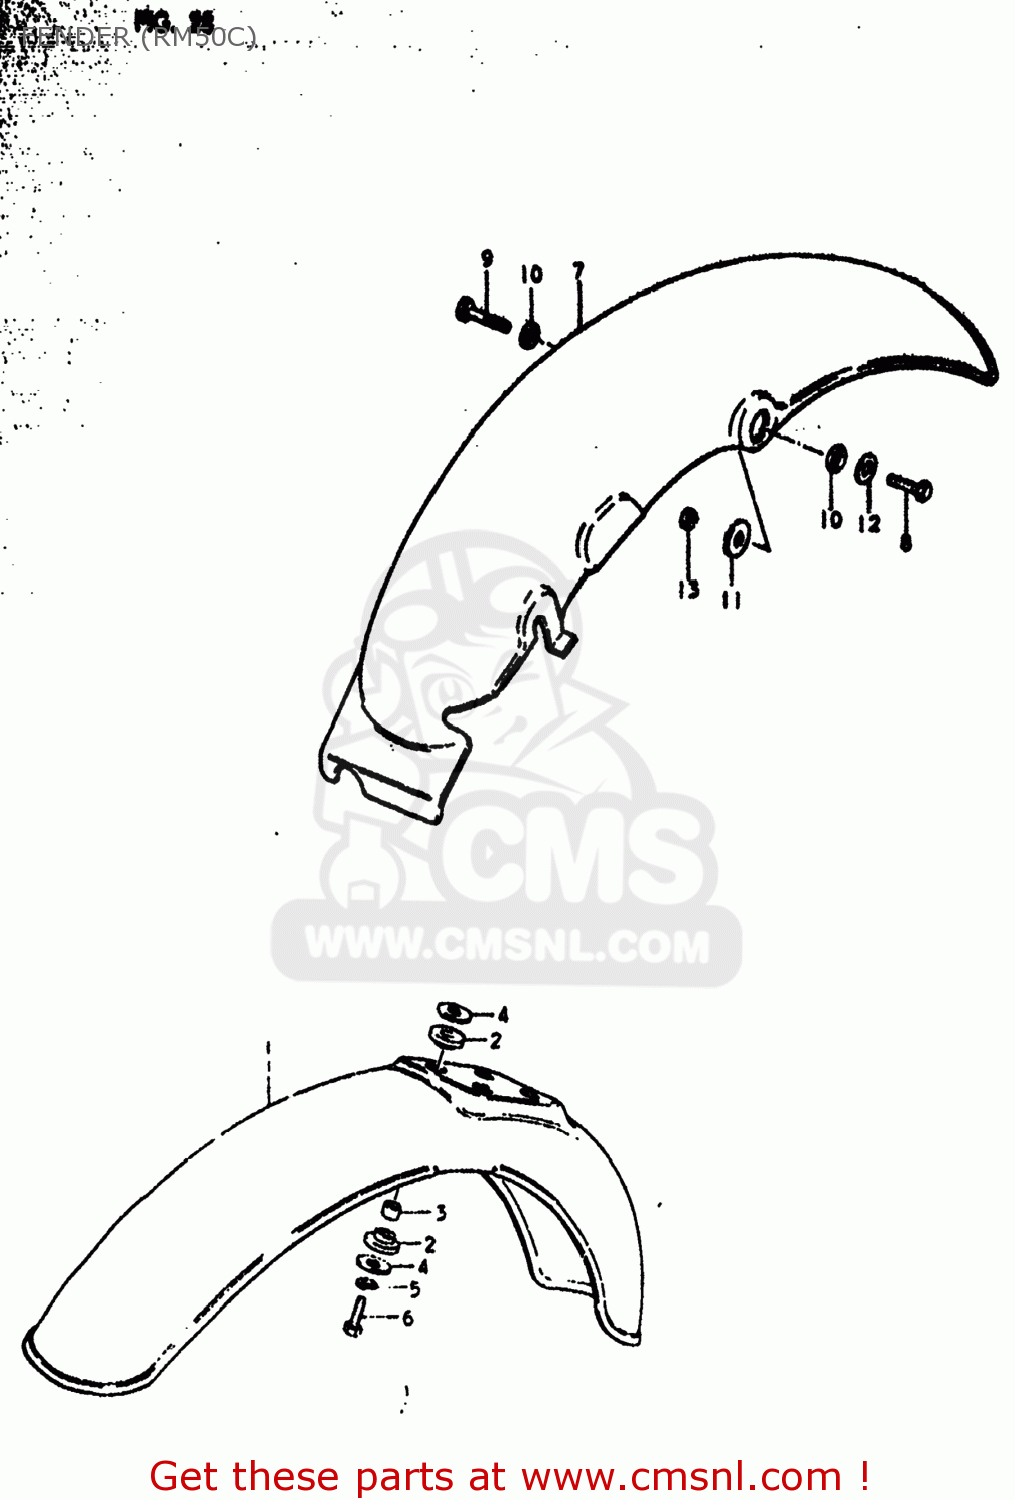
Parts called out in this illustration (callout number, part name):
1	FENDER,FRONT
2	CUSHION
3	SPACER (6.8X10X10)
4	WASHER (6.5X20X1.2)
5	LOCK WASHER
6	BOLT
7	FENDER,REAR
8	BOLT
9	BOLT (8X30)
10	SPACER(8.5X12X2.5)
11	WASHER (8.2X20X1.6)
12	WASHER
13	NUT
